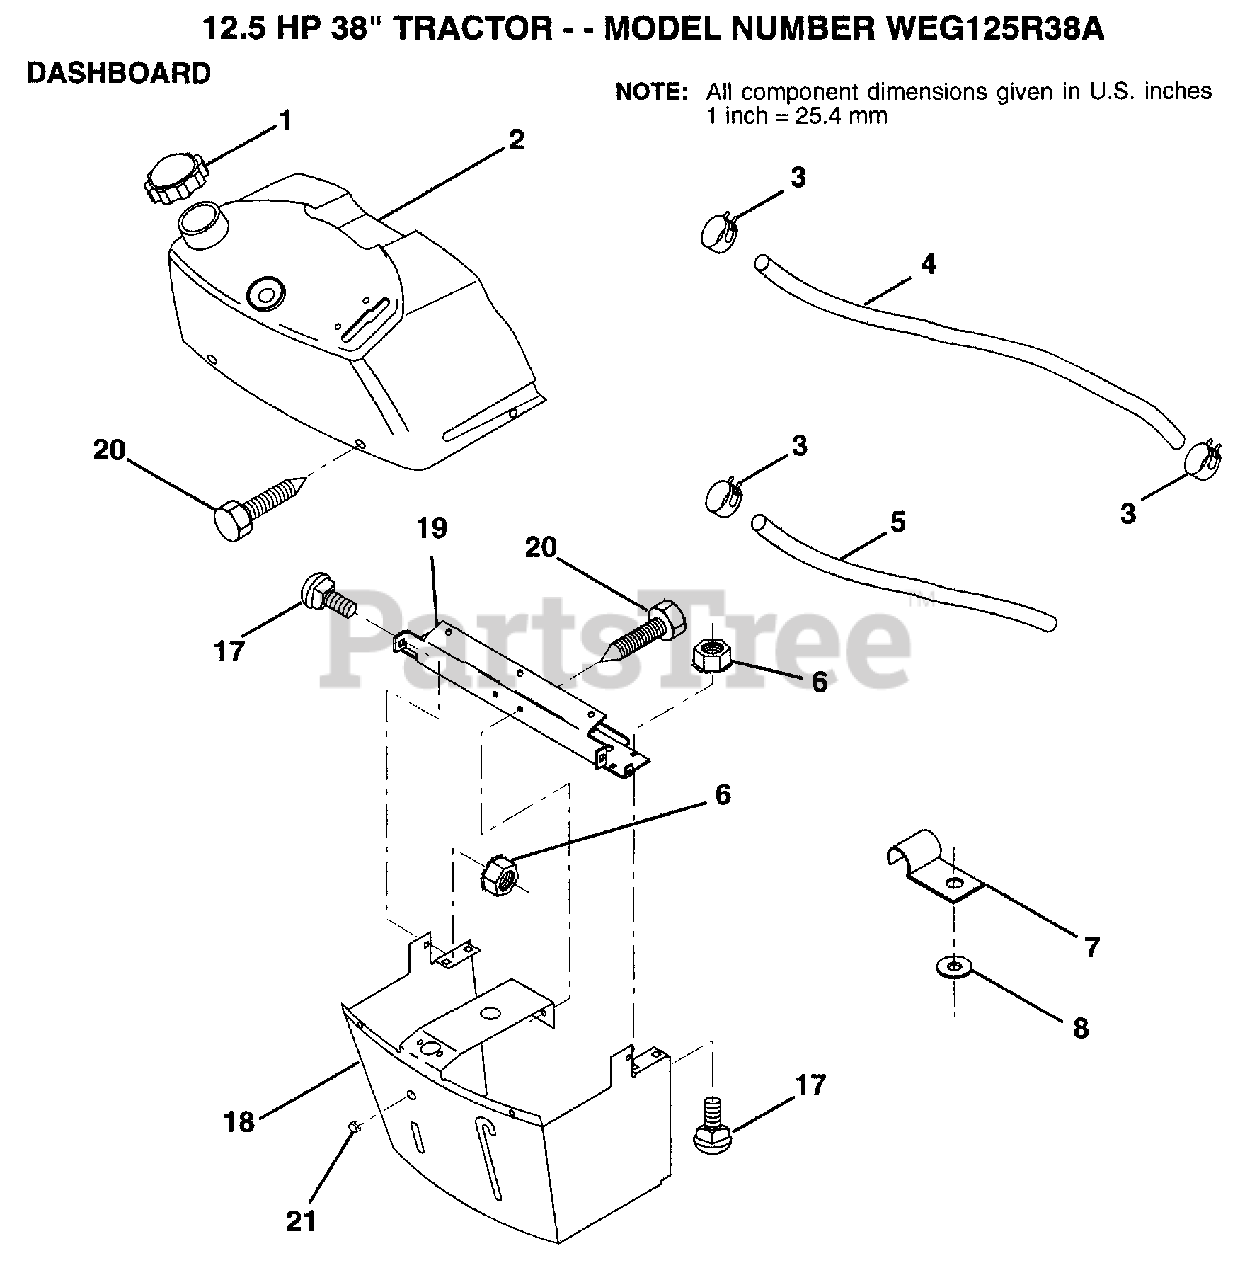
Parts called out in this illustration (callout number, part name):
1	CAP BLK FUEL LR
2	TANK.ASM.DASH.LR
3	HOSE CLAMP
5	FUEL LINE T
6	NUT
7	CLIP T
8	WASHER PM
17	BOLT
18	SUPT ASM DASH
19	CROSS BRACE
20	SCREW.1/4-20X1/2
21	PLUG DOME
